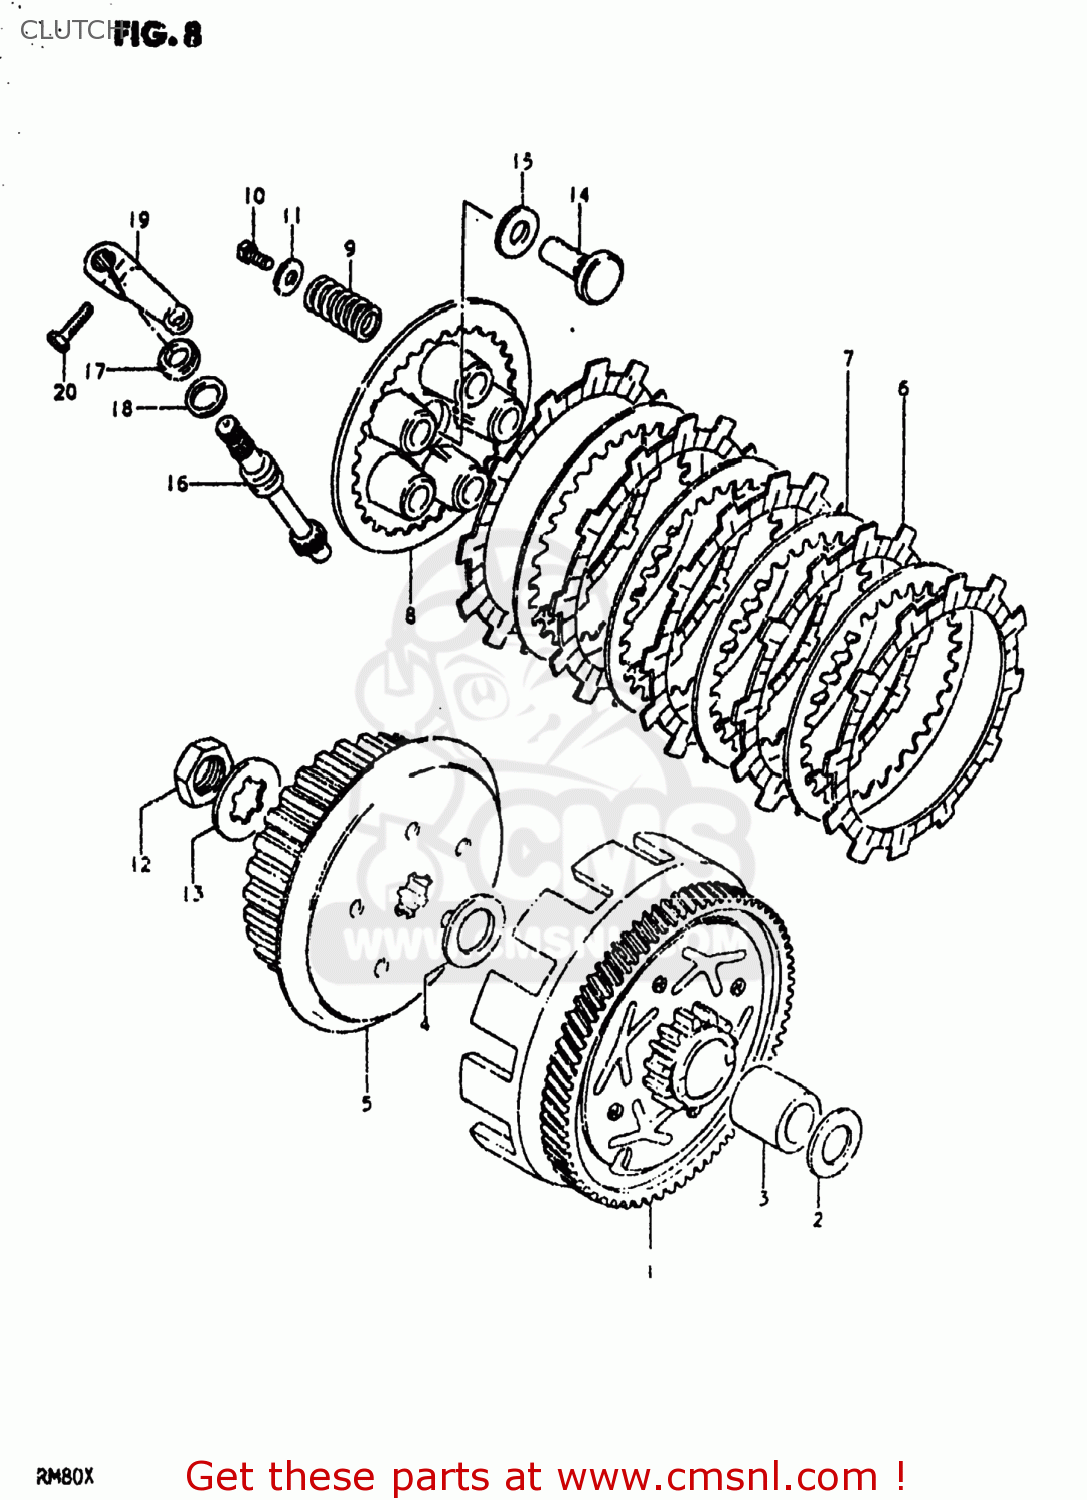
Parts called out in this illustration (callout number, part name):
1	GEAR ASSEMBLY,PRIMARY DRIVE
2	WASHER,THRUST
3	SPACER(17X22X28.5)
4	WASHER
5	HUB,CLUTCH SLEEVE
6	PLATE,CLUTCH DRIVE
7	PLATE,CLUTCH DRIVEN (NAS)
8	DISC,CLUTCH PRESSURE
9	SPRING
10	BOLT(5X16)
11	WASHER (5.5X16X1.2)
12	NUT
13	WASHER,LOCK
14	RACK,CLUTCH RELEASE
15	BEARING(10X22X2.8)
16	PINION,CLUTCH RELEASE
17	OIL SEAL
18	WASHER (12X17X1)
19	ARM,CLUTCH RELEASE
20	BOLT, UPPER
